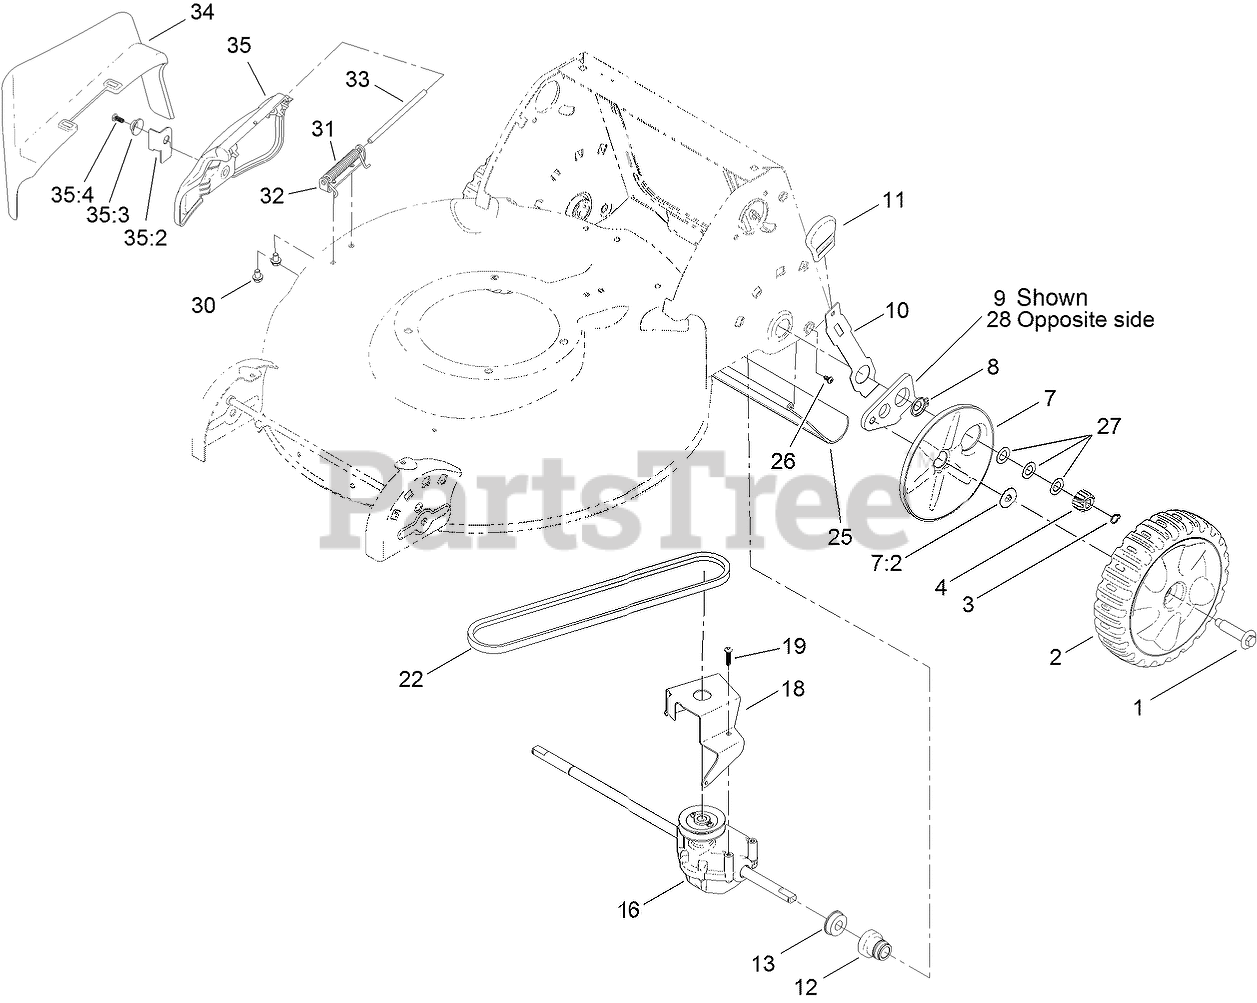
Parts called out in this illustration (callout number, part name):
1	BOLT-SHOULDER
2	8 INCH WHEEL AND GEAR ASM
3	RING-RETAINING
4	GEAR-PINION, 15T
7	WHEEL COVER ASM
7:2	WASHER-STEPPED
8	RING-RETAINING
9	ARM-REAR PIVOT, LH
10	ARM-SPRING, REAR
11	KNOB-HOC
12	RETAINER-BEARING, HOC
13	BEARING-BALL
16	TRANSMISSION ASM
18	BRACKET-TRANSMISSION
19	SCREW-PLASTITE
22	V-BELT
25	SHIELD-TRAILING
26	SCREW-PTH
27	WASHER-PLAIN
28	ARM-REAR PIVOT, RH
30	SCREW-HWH
31	SPRING-TORSION
32	BRACKET-COVER
33	ROD-COVER
34	CHUTE-DISCHARGE, SIDE
35	DISCHARGE DOOR ASM
35:2	LATCH-DOOR
35:3	CAP-DOOR
35:4	SCREW-PLASTITE
